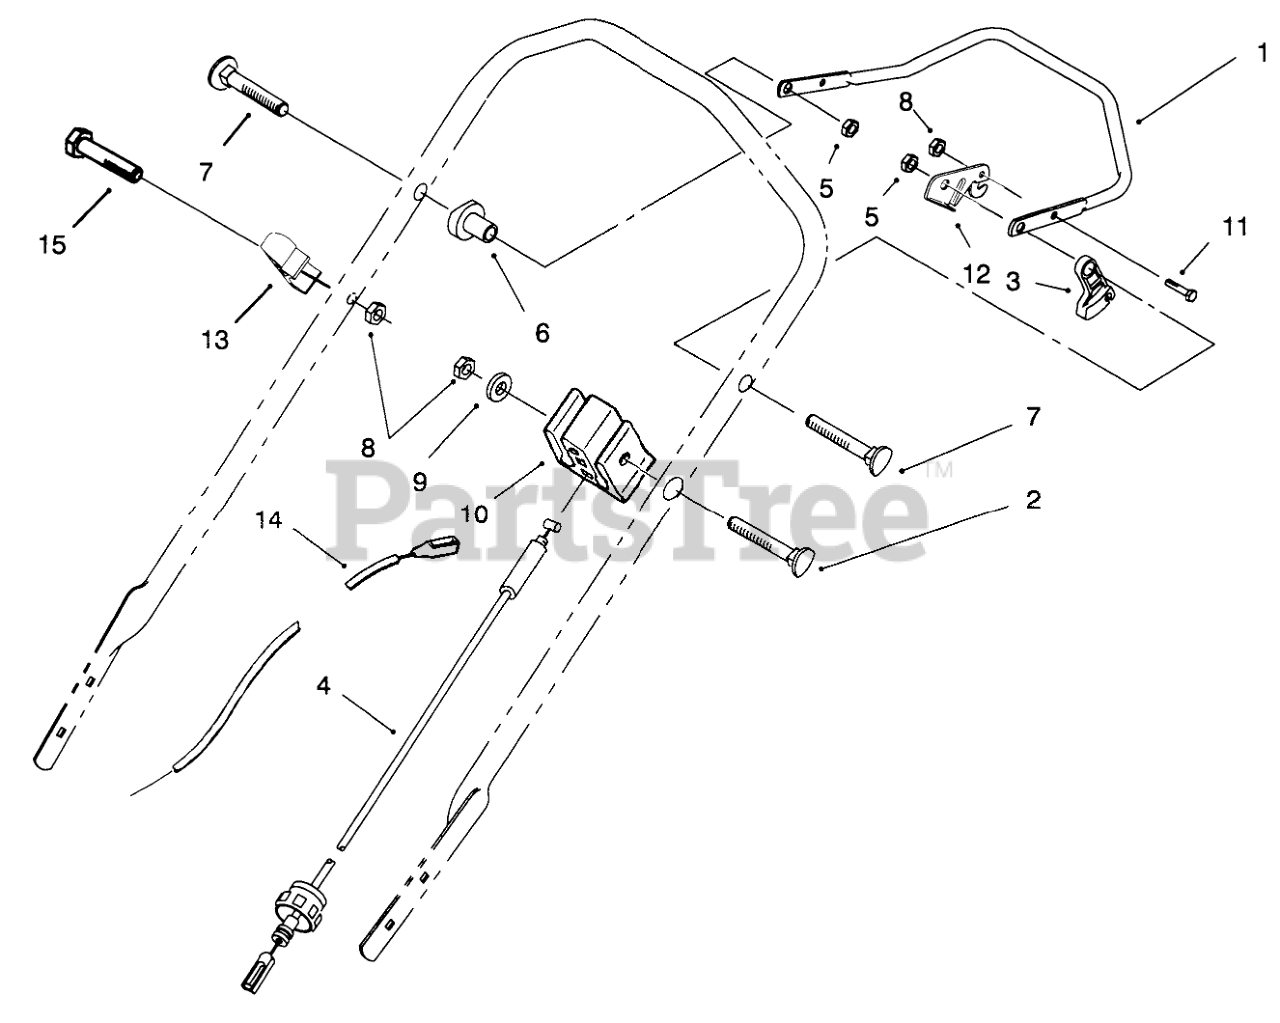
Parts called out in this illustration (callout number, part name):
1	Bar-Control
2	HANDLE SCREW
3	LEVER-TRACTION
4	CABLE-TRACTION
5	NUT-LOCK, NI
6	SPACER-SUPPORT
7	5/16-18 X 2 HNDLE SCREW
8	NUT-LOCK, NI
9	WASHER-FLAT
10	SUPPORT-CABLE
11	SCREW-HH
12	LEVER-CONTROL
13	Guide-Rope
14	BRAKE CONTROL
15	.250-20X1.625 HH SCREW
